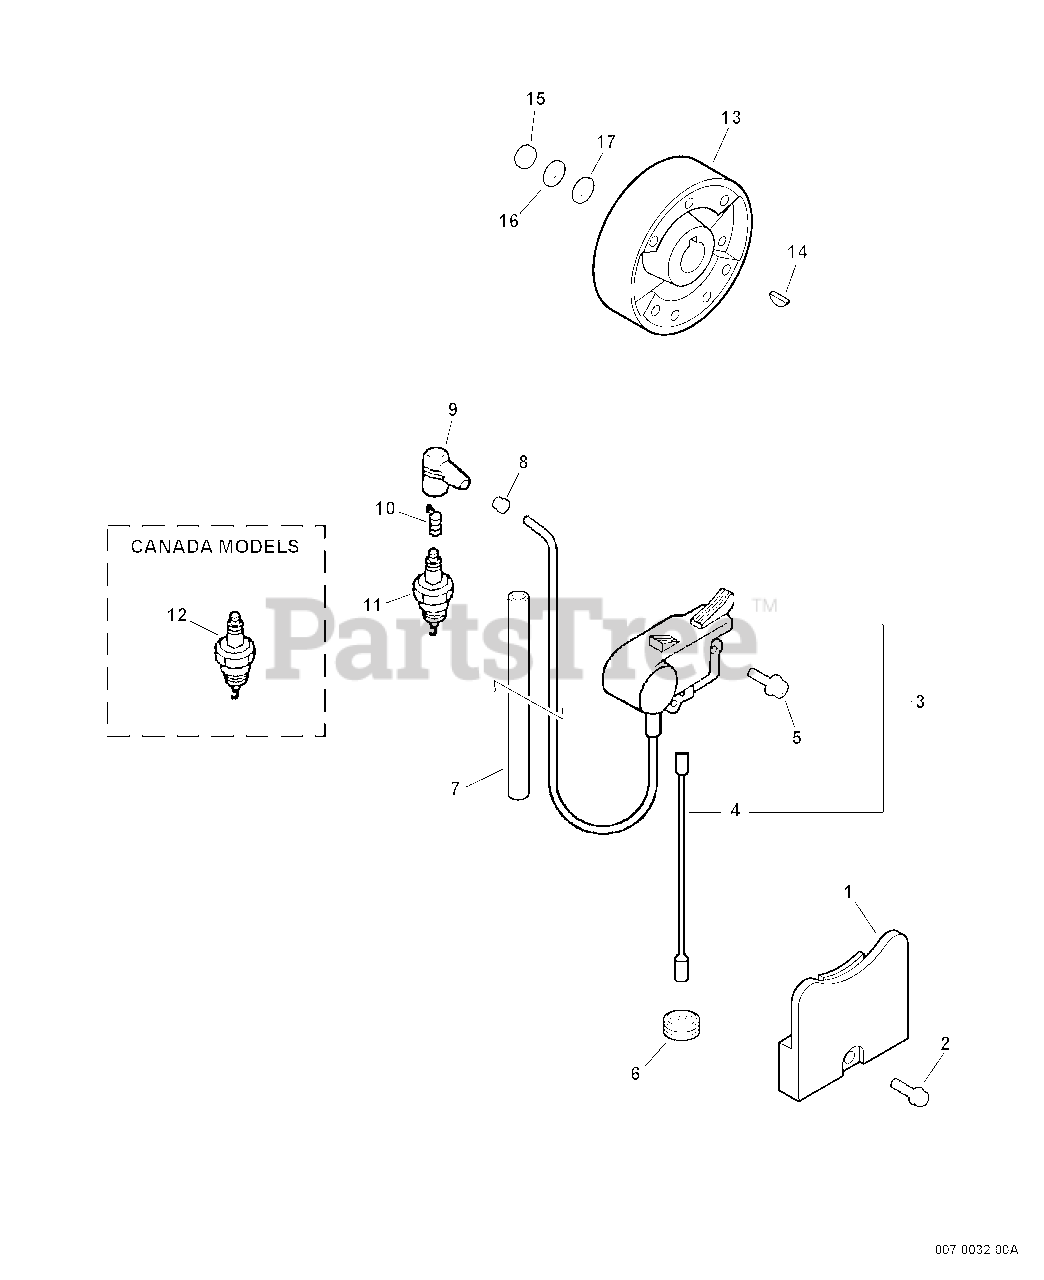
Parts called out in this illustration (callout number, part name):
1	COVER, DUST
2	SCREW - 5X18
3	COIL, IGNITION
4	LEAD - IGNITION
5	SCREW - 5X18
7	TUBE - VINYL
8	ADAPTER, SPARK PLUG CAP
9	CAP, SPARK PLUG
10	TERMINAL, SPARK PLUG CAP
11	SPARK PLUG -- BPM-7Y
12	SPARK PLUG -- BPMR-7A
13	FLYWHEEL
14	KEY - 3X14
15	NUT - 10
16	LOCKWASHER - 10
17	WASHER - 10
